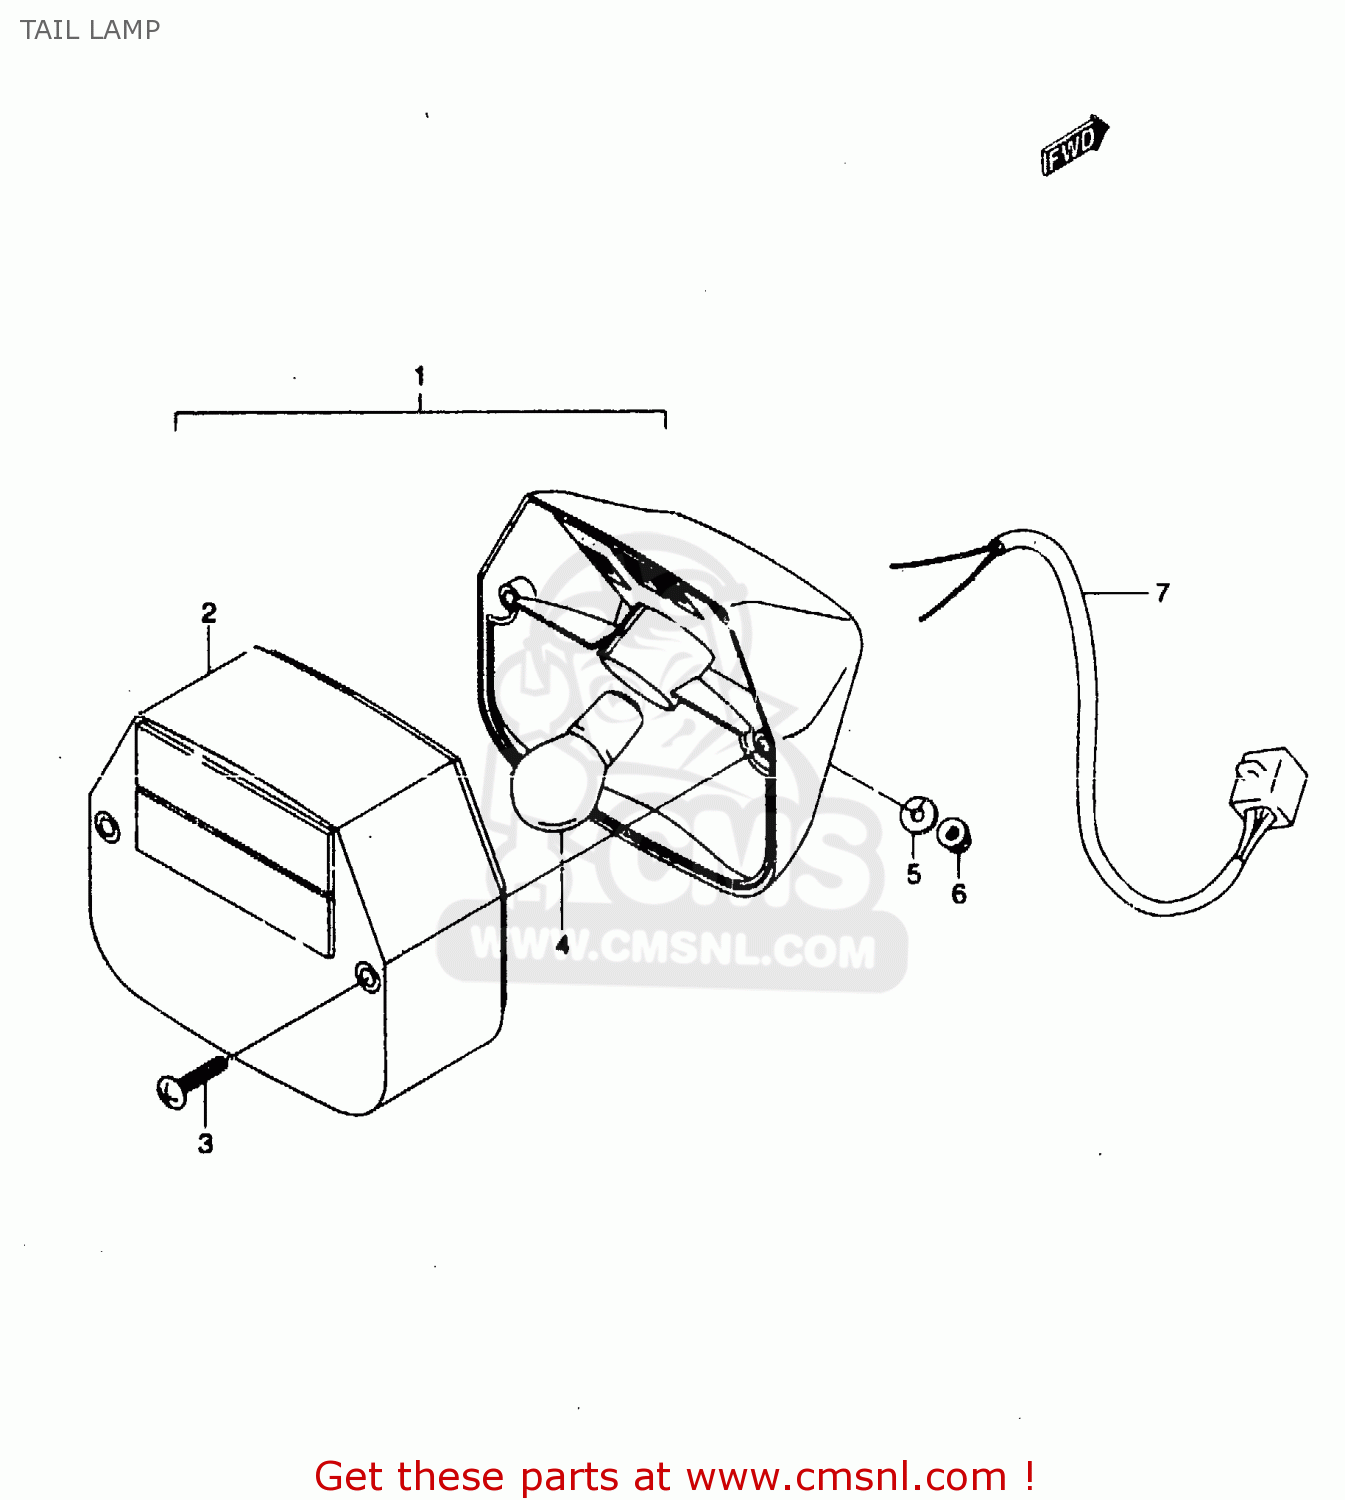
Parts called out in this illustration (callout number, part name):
1	LAMP ASSY, TAIL
2	LENS
3	SCREW
4	BULB(12V21/5W)
5	WASHER
6	NUT
7	WIRE, TAIL LAMP
